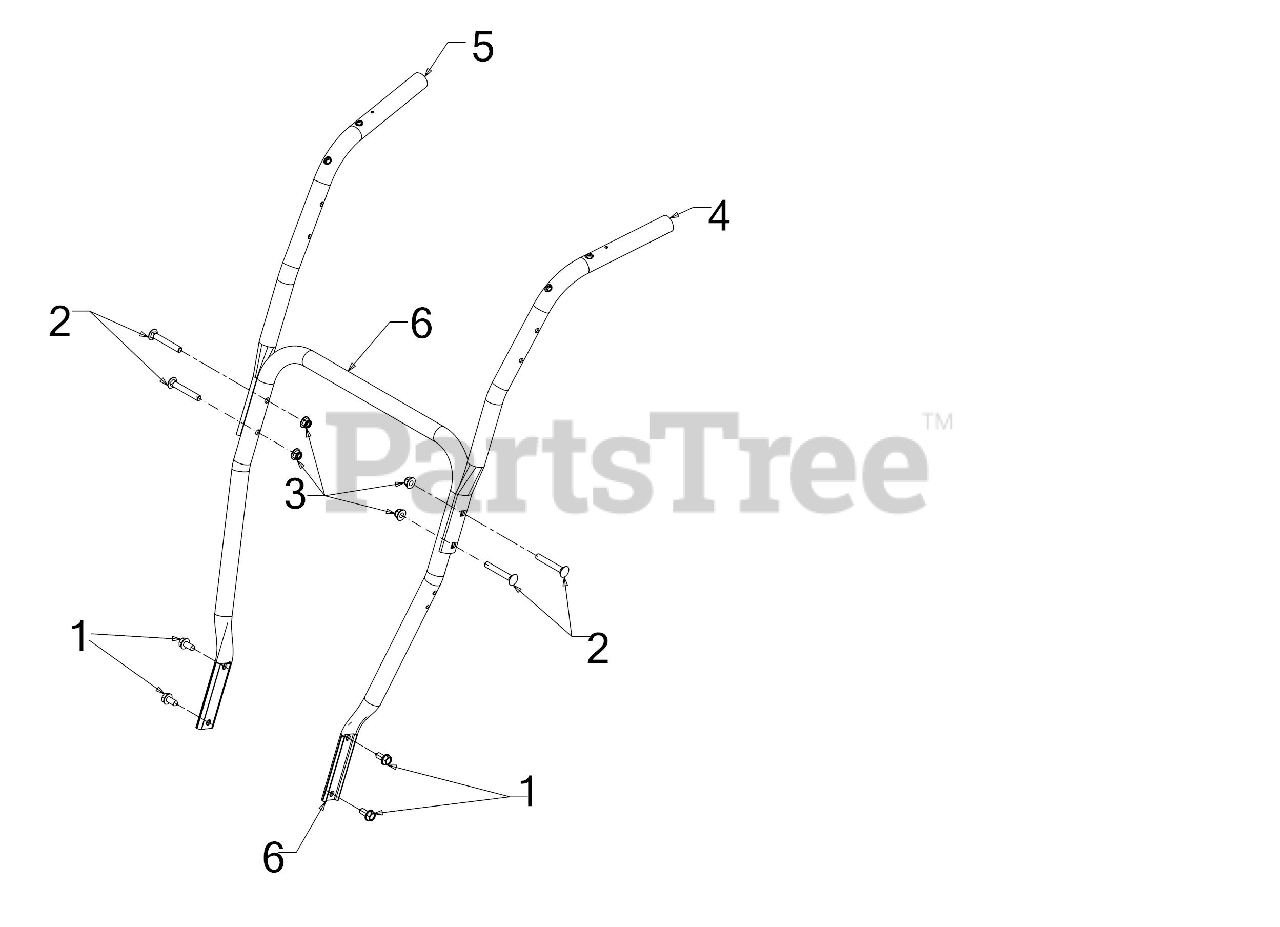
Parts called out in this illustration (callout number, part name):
1	SCREW 5/16-18 x .750
2	SCRE W5/16-18 x 2.25 GR5
3	FLANGE LOCK NUT 5/16-18
4	UPPER HANDLE (LH)
5	UPPER HANDLE (RH)
6	LOWER HANDLE
